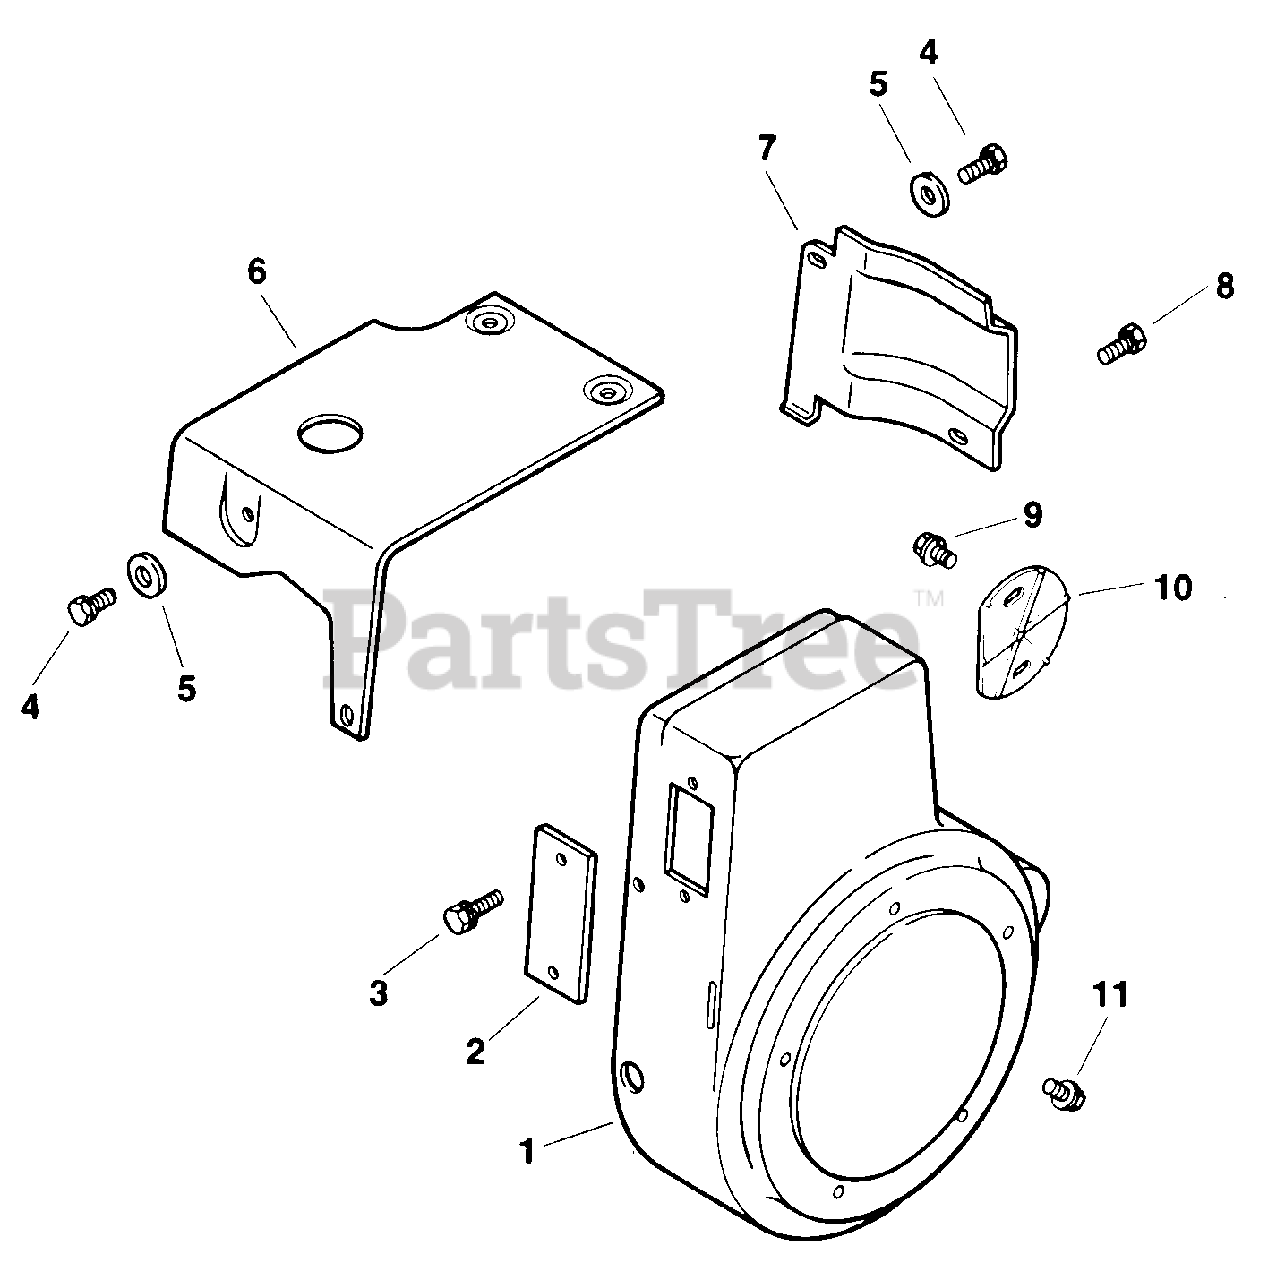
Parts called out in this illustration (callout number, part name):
1	Housing, Blower
2	Cover, Rectifier-Regulator
3	Screw, H.C. 1/4-20 x 1
4	Screw, H.C. 1/4-20 x 3/4
5	Washer, Plain 1/4
6	Baffle, Head
7	Baffle, Cylinder
8	Screw, H.C. 1/4-20 x 3/4
9	Screw, Pozidrive T.H. 1/4-20 x 5/8
10	Cover, Starter
11	Screw, H.C. 1/4-20 x
